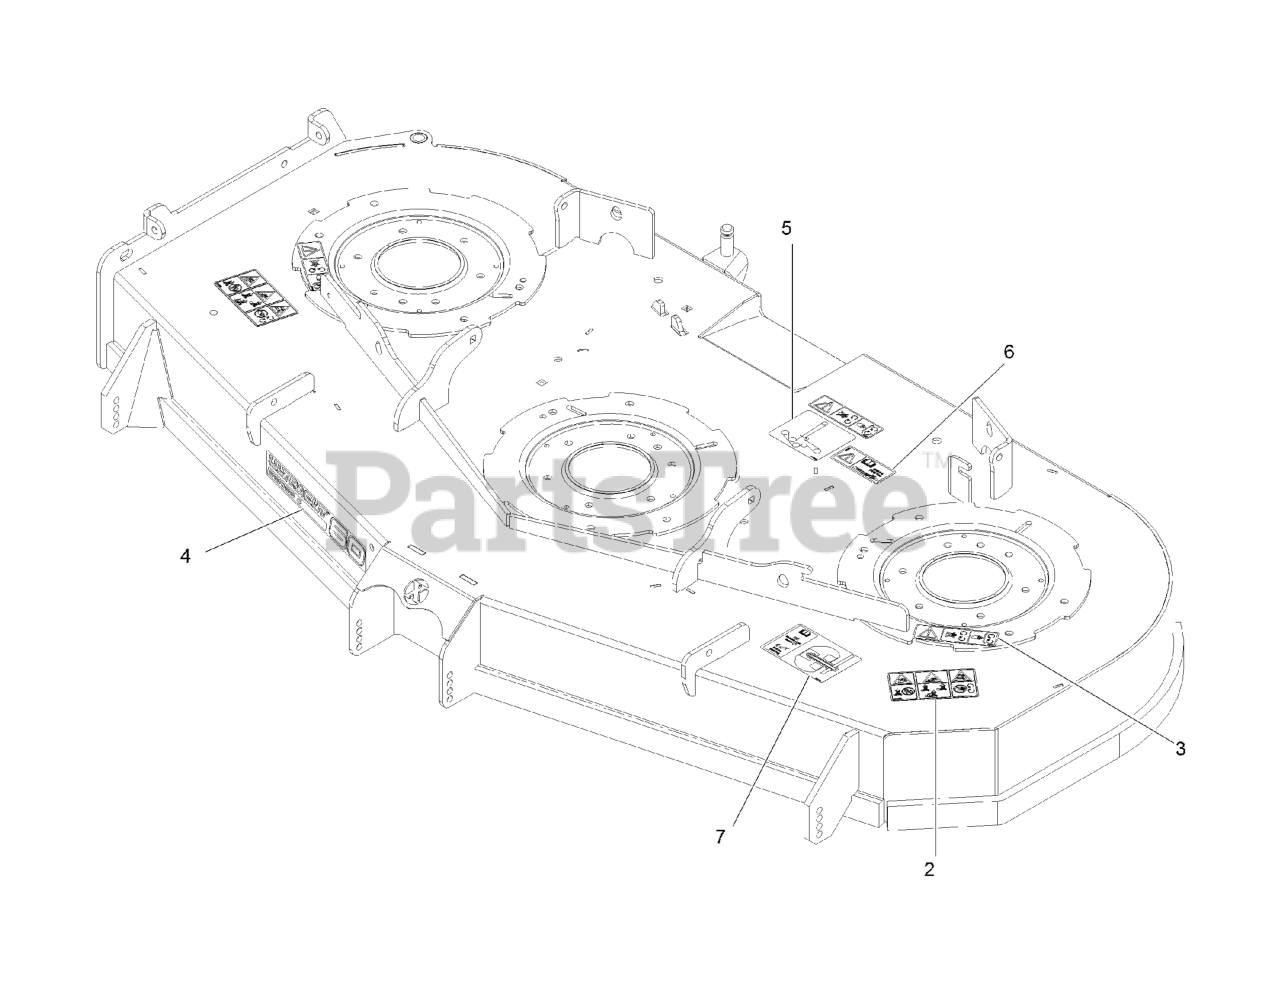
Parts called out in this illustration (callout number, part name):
2	DECAL-WARNING THROWN OBJ
3	DECAL-COVER, MISSING
4	DECAL, 604
5	DECAL-BELT ROUTING
6	DECAL-TORQUE, BOLT
7	DECAL-ROLLER MOUNTING
